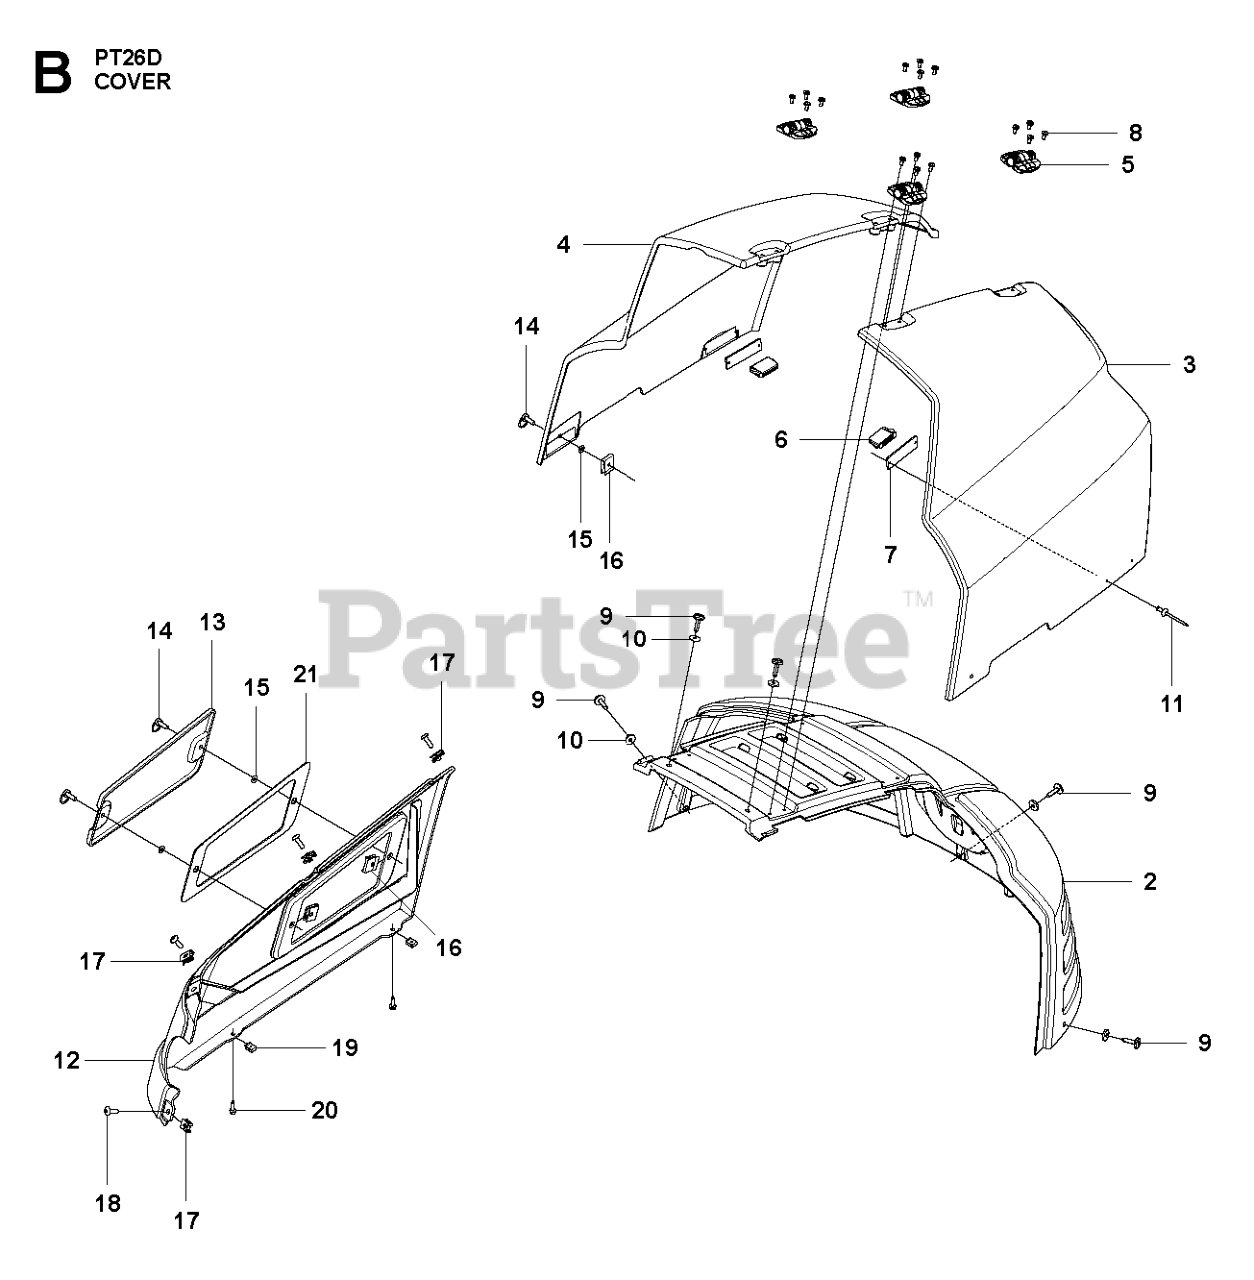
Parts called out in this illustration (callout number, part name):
2	ENGINE HOOD CENTRE PART
12	COVER CONTROL COVER SIDE ASSY
14	BOLT
21	GASKET SIDE COVER
